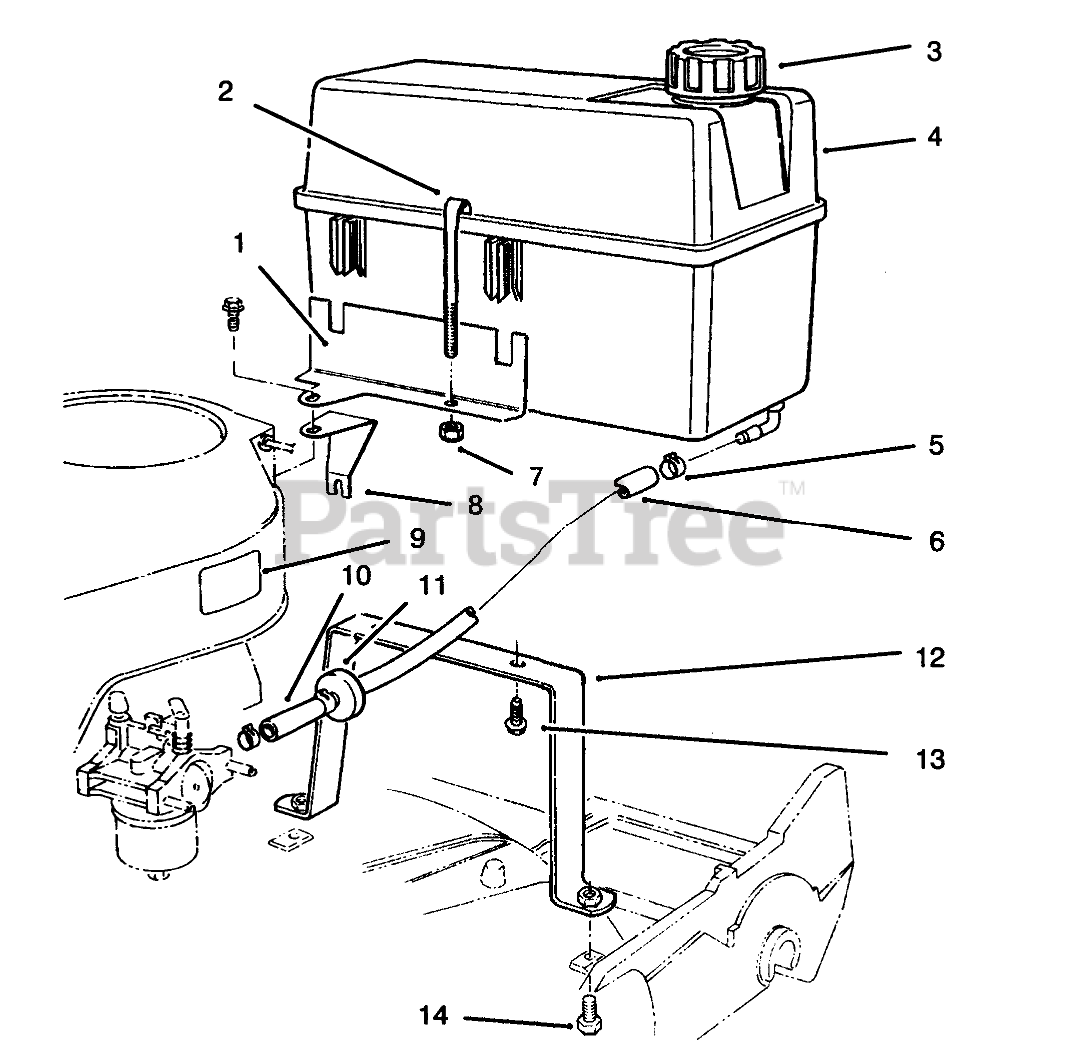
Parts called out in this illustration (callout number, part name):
1	Bracket Tank
2	RETAINER - FUEL TANK
3	GAS CAP ASM
4	Tank-Gas
5	CLAMP-FUEL LINE
6	HOSE-FUEL
7	NUT-LOCK, NI
8	Support-Bracket
9	DECAL - FUEL
10	LINE-GAS
11	FILTER-FUEL
12	Base-Tank
13	SCREW-HWH
14	SCREW-HH
